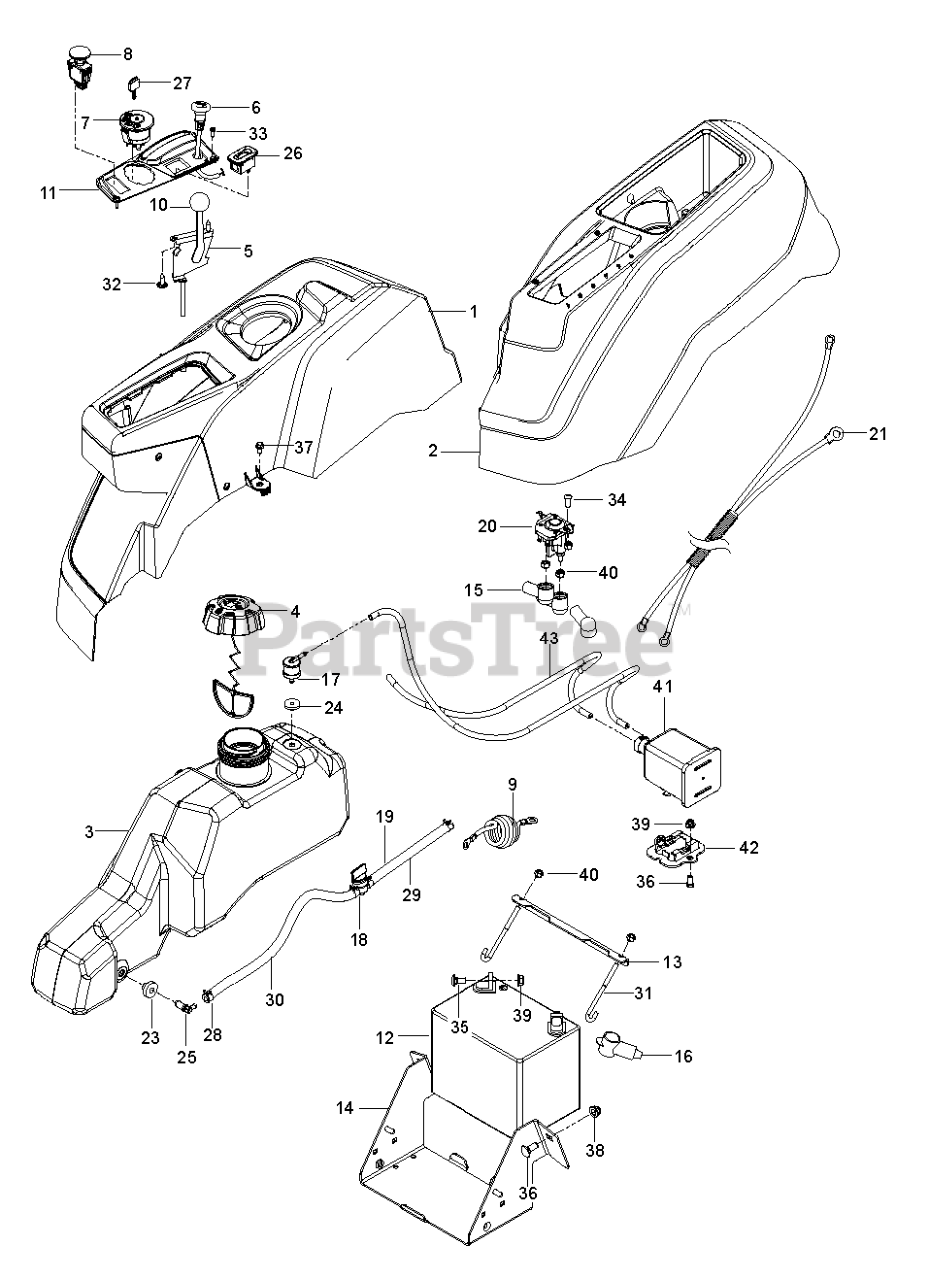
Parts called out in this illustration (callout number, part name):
1	CONSOLE.ASSY.RZ.REFRESH.RH
2	CONSOLE.LH.ASM
3	TANK.ASM3"NECK.NOCAP.NOSHDRZ18
4	Fuel Caps
4	FUEL CAP
5	THROTTLE CABLE
6	CHOKE.PUSH-IN.STYLE
7	RP IGNITION SWITCH
8	RP SWITCH.PTO.TERMINAL.STD.RED
9	CABLE BATTERY POS RZ
10	KNOB.ROUND.BALL.BLACK
11	CONTROL.PANEL.RZ.REFRESH.RH
12	BATTERY WET NOT SELLABLE
13	BRACKET.PNT.MOUNT.BATTERY.EDIP
14	BOX.PNT.BATTERY.RZ.EDIP
15	TERMINAL COVER
17	VALVE.FUEL.CHECK
18	FUEL VALVE
19	FUEL.HOSE.SHUT.OFF.ASM.10".3"
20	SOLENOID.STARTER.BRASS.PLUNGER
21	HARNESS.BTTRY.CABLE.RZ.REFRESH
23	BUSHING OUTLET T
24	GROMMET.ROV.SENTEC
25	STEM FUEL TANK
26	GUAGE.SRVCMNDR.HRMTR.
27	KEY.CHAIN.BLISTER.PACK.GEN.USA
28	HOSE CLAMP
29	HOSE.1/4".LOW.PERM.FUEL.LN.10"
30	HOSE 1/4" LOW PERMEATION FUEL
31	HOOK.J.BATTERY
32	SCREW.PAN.HEAD.#10
33	SCREW 6-19X.437
34	SCR 1/4-20 X 5/8 BTN SKT HD ZD
35	BOLT 5/16C X 3/4" CARRIAGE
36	RHSNB 3/8C X 1
37	SCREW
38	NUT 3/8-16 HEX FLG NYLOC ZD
39	5/16-18 NYLOC FLANGE NUT
40	NUT.1/4-20.HEX.NYLOC.ZD
41	CANNISTER, CARBON
42	BRACKET, CANISTER
43	RP PURGE LINE
